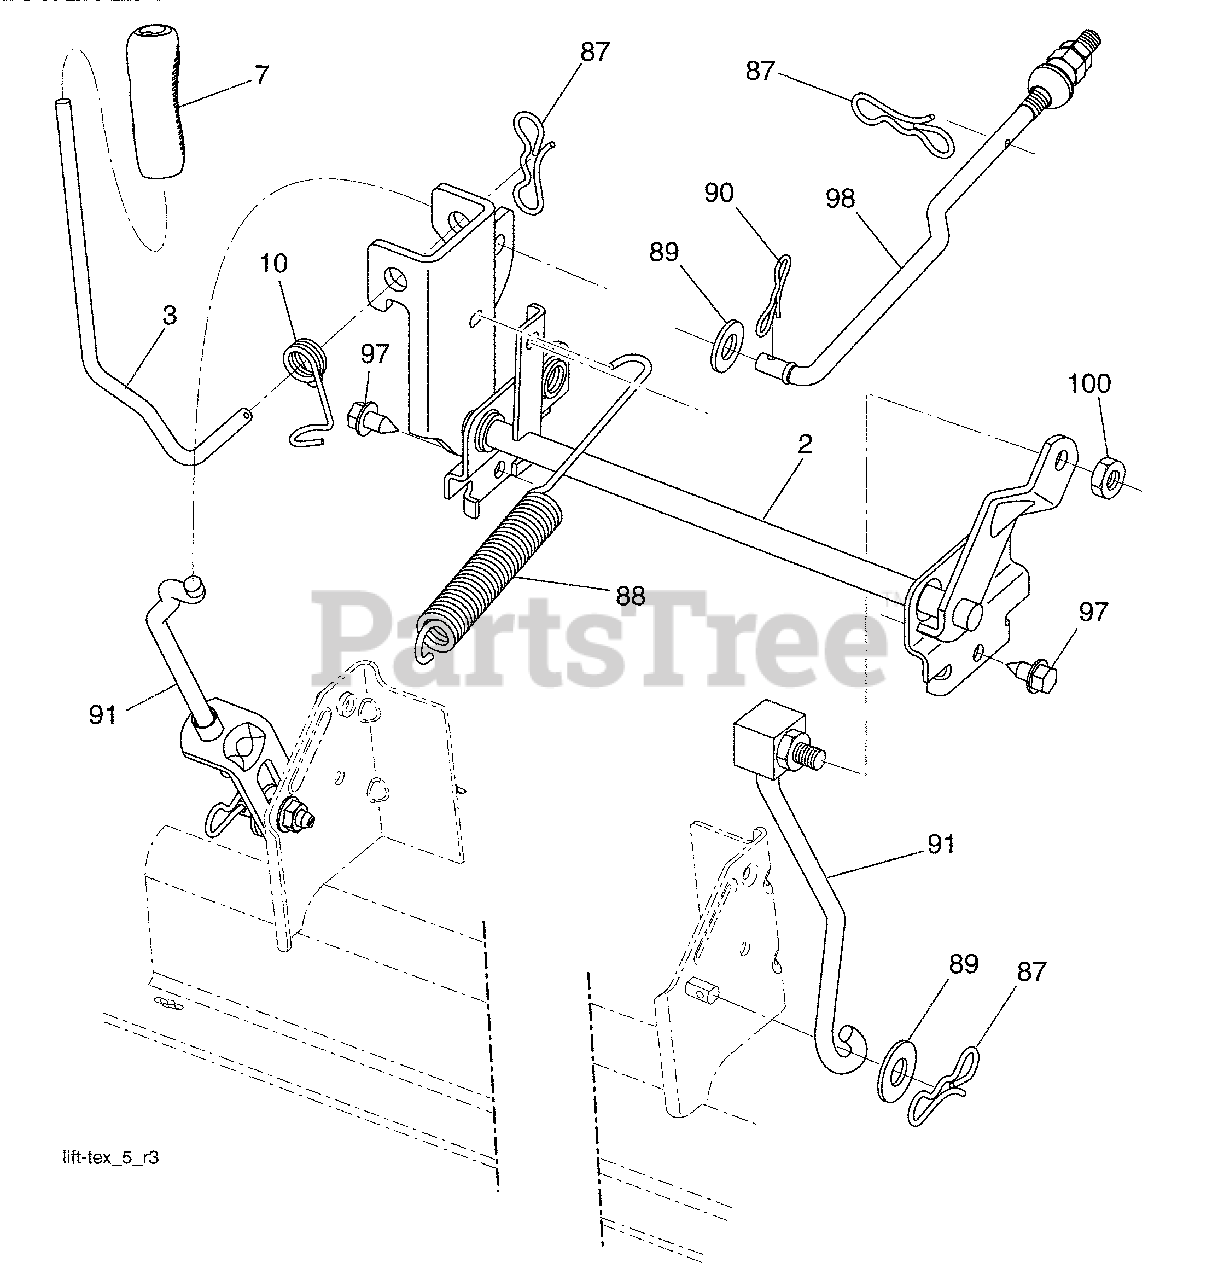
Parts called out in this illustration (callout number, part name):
2	Shaft Asm., Lift
3	Lever Asm., Lift RH
7	Grip, Lever
10	Spring Torsion
87	Pin Cotter 7/16 Bow Tie Lock
88	Spring Lift Assist
89	Washer Clear Zinc
90	Pin Cotter 5/16 Bow Tie Lock
91	Link Lift Susp Mower Rear
97	Screw 3/8-16 x 3/4
98	Link Asm. Susp. Front Mower
100	Nut Centerlock 3/8-16 unc
113	Washer 17/32 x 1-3/16 x12 Ga.
